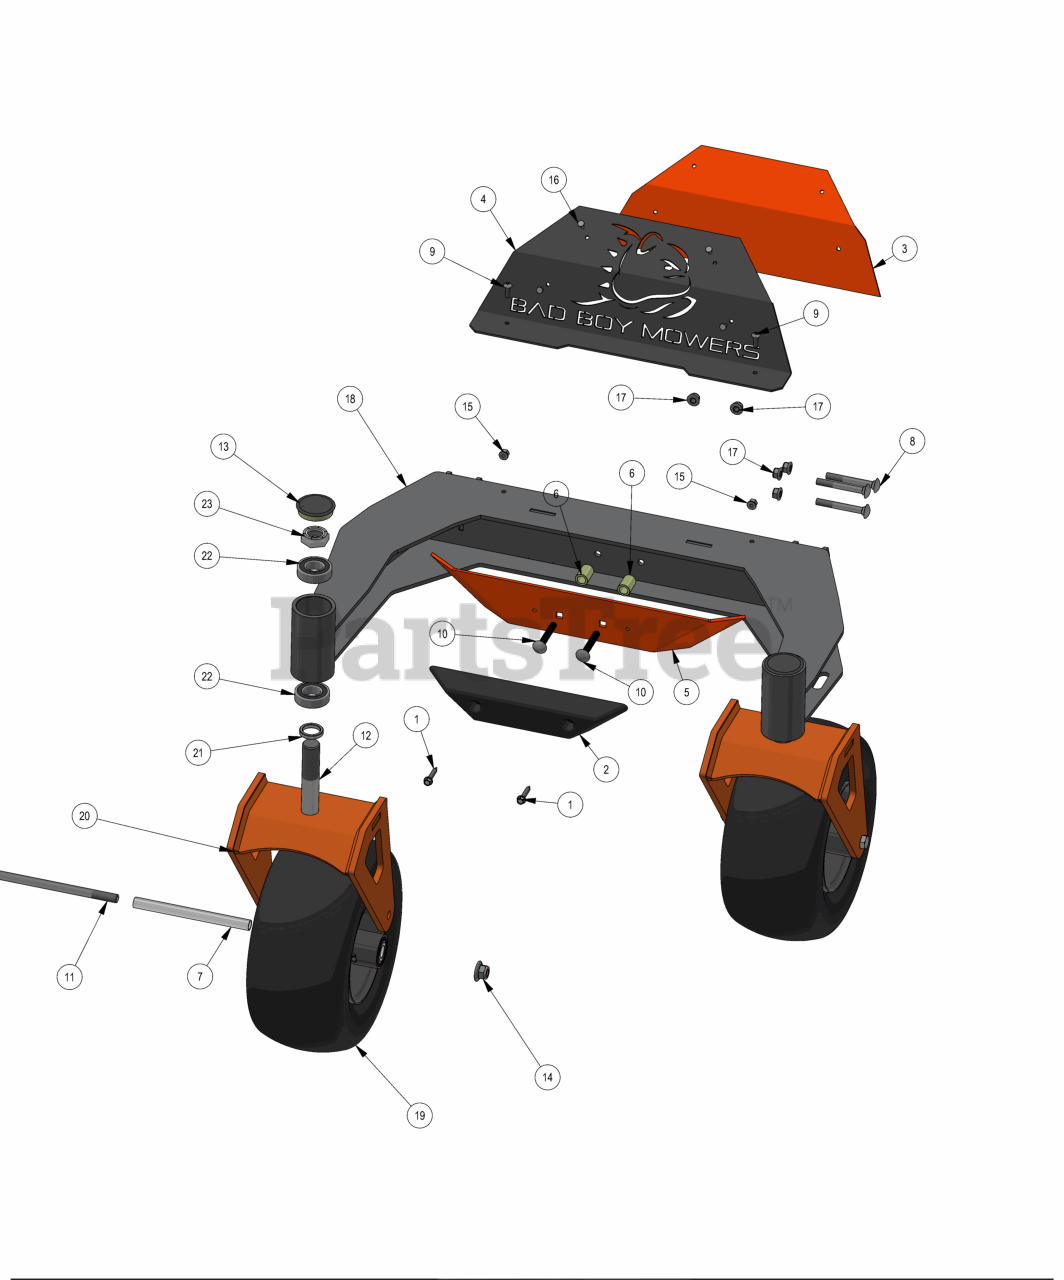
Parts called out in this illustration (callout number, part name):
1	1/4-14 X 1-1/2 HEX WASHER UNSLOT TEK/3 ZINC
2	Bumper EZT
3	Exhaust Backer Plate 2019 Stand On
4	Exhaust Shield Plate 2019 Stand On
5	2019 Stand On Front Bumper Plate
7	Front Wheel Spanner
8	3/8-16 X 3 CARRIAGE BOLT ZINC GR5
9	1/4"-20 x 3/4 Black Oxide 18-8 Stainless Pan Head
10	3/8" x 2 1/2" Carriage Bolt
11	1/2-13 X 8-1/2 HEX CAP SCREW (GR.5) ZINC
12	1"-14 X 5 HEX CAP SCREW (GR.8) ZINC YELLOW
13	2017 Bearing Cover
14	1/2-13 NYLON INSERT FLANGE LOCKNUT ZINC
15	1/4-20 Nylon Insert flange Nut
16	3/16" Diameter Black Rivet, for 0.1260"-0.25" Material Thick
17	3/8" Nylock Flange Nut
18	2023 36 Stand-On Front End Weldment
19	13x6.50-6 Black No Flat Assembly
20	2019 Stand-on Front Fork Weldment
21	Spacer, 1x1.375x.25
22	1641 BEARING W/2 CONTACT RUBBER SEALS
23	1" Fine Thread 1/2 Nylock Nut
